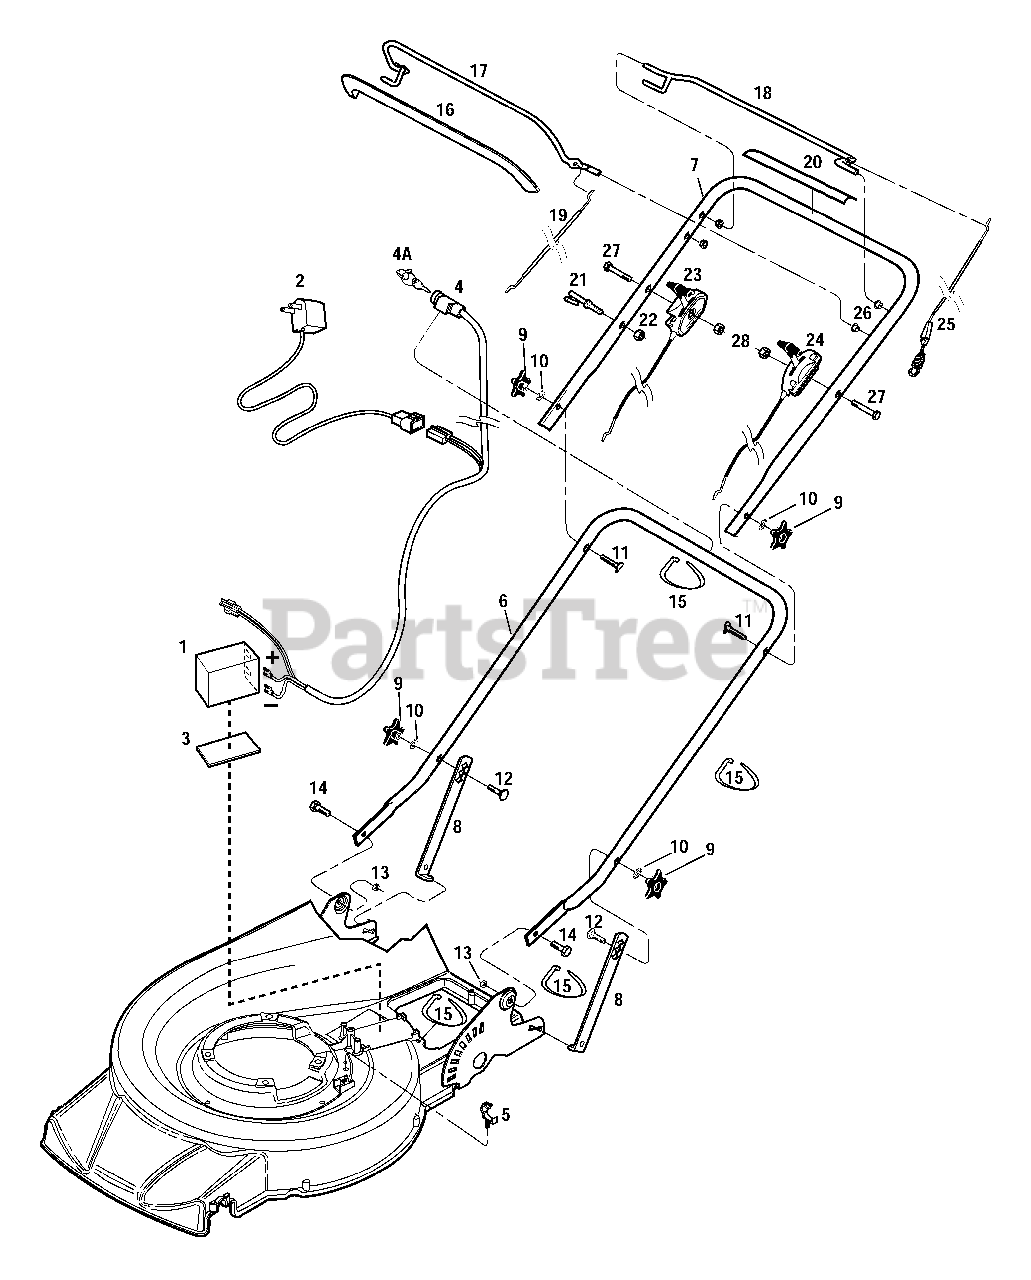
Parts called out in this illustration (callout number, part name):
1	Battery
2	Battery Charger Kit
3	Battery Pad
4	Keyswitch and Wire Harness
4A	Key
5	Wire Harness Clip
6	Lower Handlebar
7	Upper Handlebar
8	Handlebar Support Strut
9	Handlebar Adjustment Knob
10	Ext. Tooth Lock Washer, 5/16
11	Curved Head Screw, 5/16-18 x 1-3/4
12	Carriage Bolt, 5/16-18 x 1-3/4, Special
13	Hex Lock Nut, 3/8-16
14	Hex Hd. Screw, 3/8-16 x 3/4, GR. 5
15	Cable Tie
16	Bail Grip
17	Operator Presence Control Bail
18	Wheel Drive Bail
19	Operator Presence Control Cable
20	Decal - Bail Operating Instructions
21	Rope Guide
22	Hex Flange Nut, 1/4-20
23	Throttle Control Lever/Cable
24	Speed Control Lever/Cable
25	Drive Control Cable
26	Bushing, Nyliner
27	Hex Hd. Screw, M6
28	Hex Nut, M6
